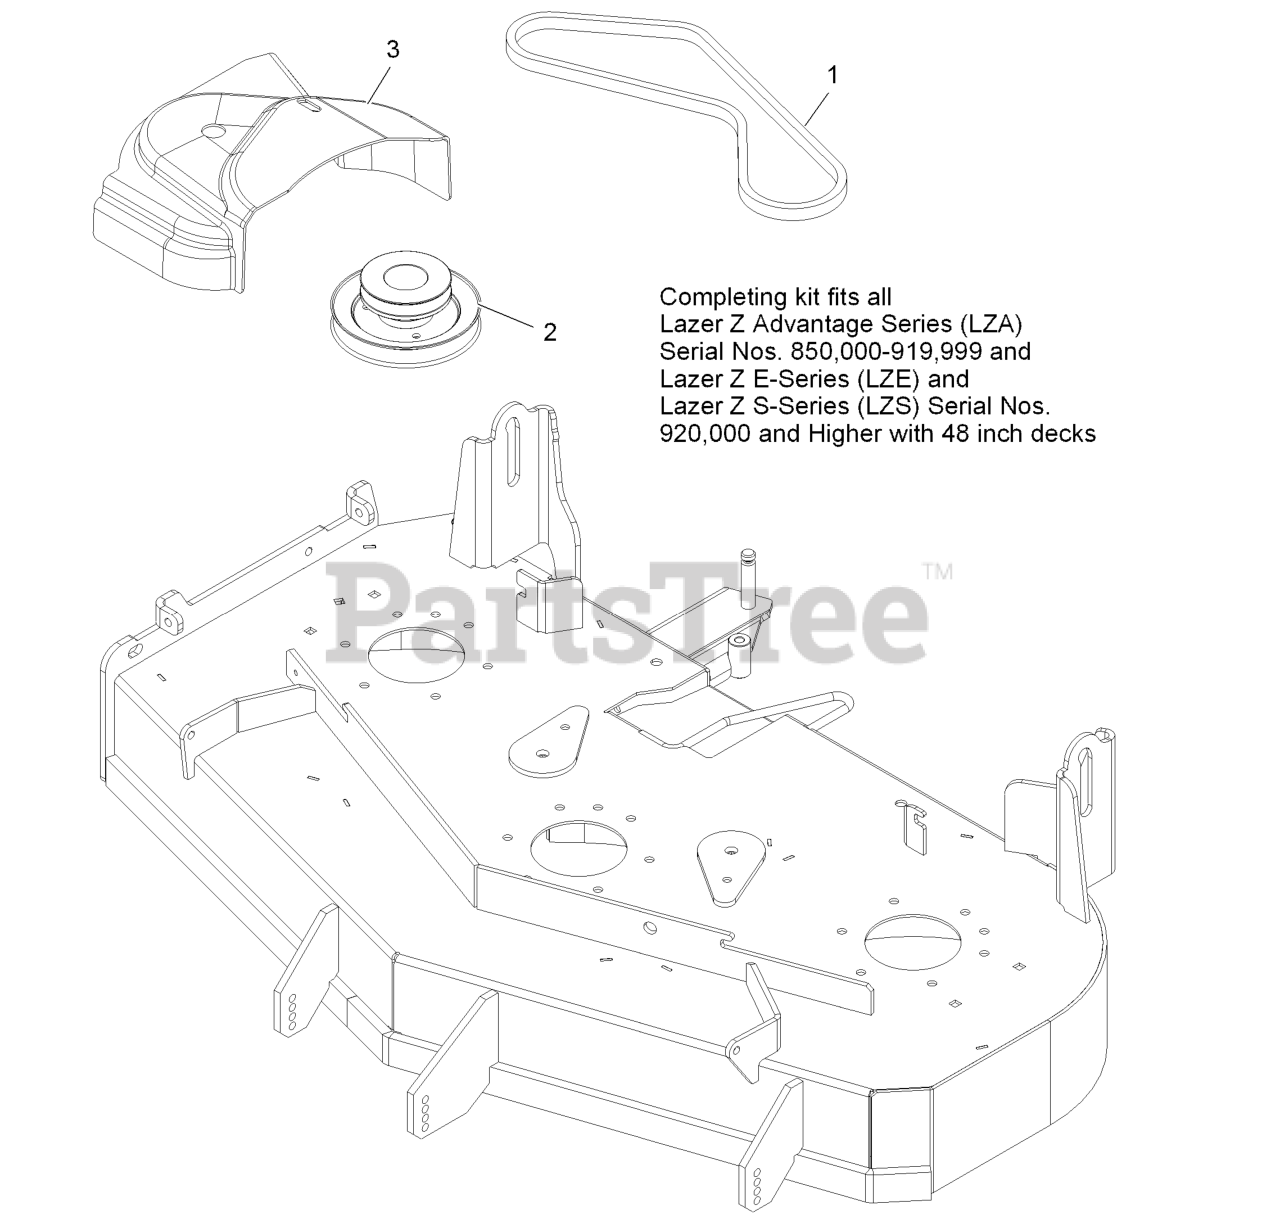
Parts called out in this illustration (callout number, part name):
1	BELT-BLOWER
2	JACKSHAFT-UV DRIVE, 484 S
3	COVER,BELT UV 48
